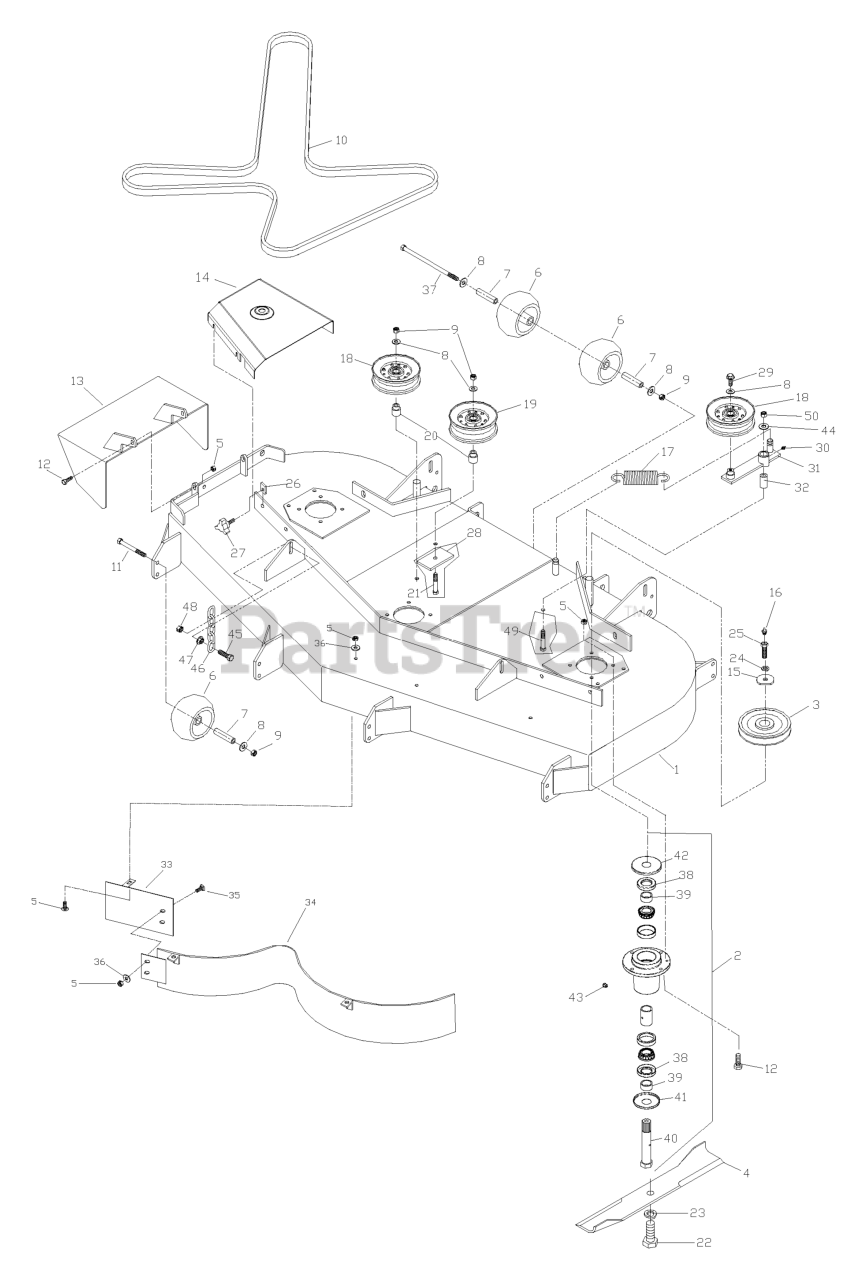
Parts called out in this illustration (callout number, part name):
1	DECK W/DECALS 72" HUS WSL
2	SPINDLE ASSY - 72"
3	RP PULLEY - 72"
4	BLADE OEM - 25"
5	NUT 5/16C CENTERLOCK
6	ANTI-SCALP ROLLER
8	WASHER 3/8 FLAT
9	NUT 3/8C CENTERBLOCK
10	BELT, DECK 72"
11	HCS 3/8C X 3 1/2
12	HCS 5/16C X 1
13	DISCHARGE CHUTE
14	SHIELD BELT RIGHT ORANGE
14	SHIELD BELT LEFT ORANGE
15	SPINDLE WASHER
16	ZERK
17	DECK SPRING
18	IDLER PULLEY
19	IDLER PULLEY (TALL)
20	IDLER BUSHING
21	HCS 3/8C X 2 1/2
22	HEX SCREW-5/8F X 2 GR8
23	BELLEVILLE SPRING WASHER
24	WASHER 7/16 LOCK
25	DRILLED BOLT 7/16-20 X 1 1/2"
26	U-CLIP 5/16-18 NUT RETAINER
27	KNOB W/STUD
28	SUPPORT PLATE
29	4CS 3/8C X 1 SERRATED HEAD
30	ZERK
32	PIVOT BUSHING
33	BAFFLE/CENTER-FLAT BLK
34	BAFFLE/CENTER-CURVED
35	CARRIAGE BOLT 5/16C X 5/8"
36	WASHER 5/16 FLAT
37	BOLT 3/8 X 6" GRD 8
38	SHAFT SEAL
40	SPLINED SHAFT - 72"
41	BOTTOM DUST CAP
42	TOP DUST CAP
43	PLUG-VENTED
44	WASHER 1/2 FLAT
45	HCS 7/16C X 1 1/2
46	LIFT CHAIN
47	NUT 7/16C WHIZ
48	NUT 7/16C CENTERLOCK
49	HCS 1/2C X 3 1/4
50	NUT 1/2-13 HEX NYLOC ZD
